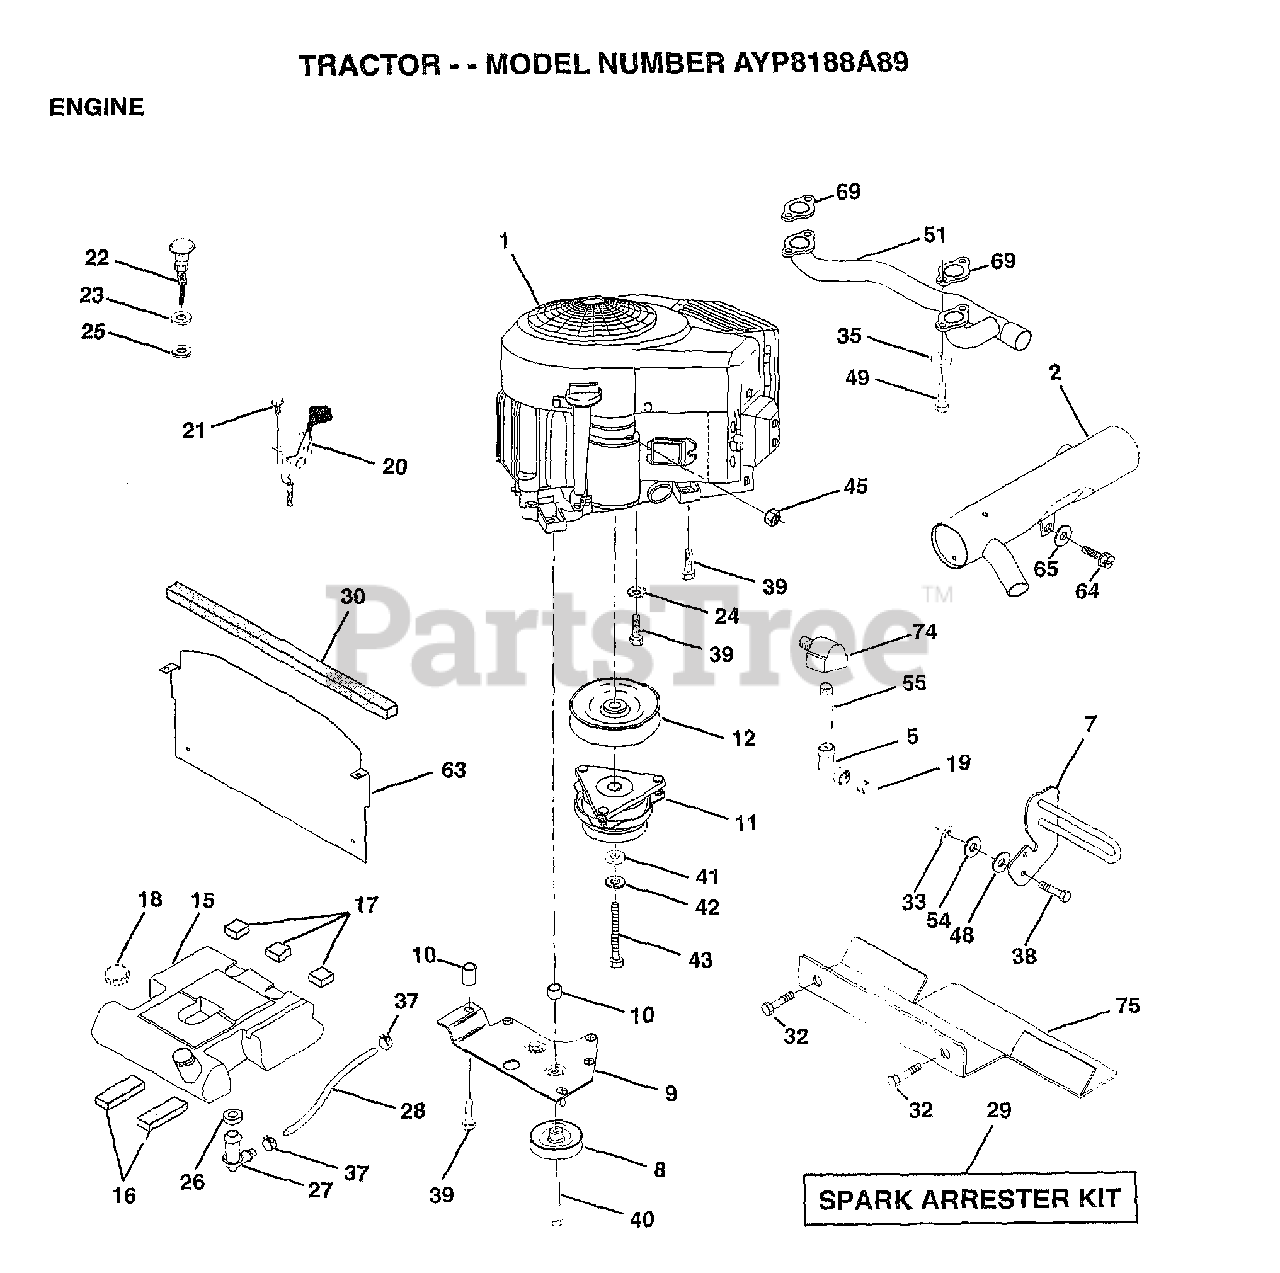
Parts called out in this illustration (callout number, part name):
2	MUFFLER SIDE1-1/8
4	PIPE NIPPLE LT
5	ELBOW
7	GUARD.MUFFLER.ASM
9	KEEPER ASM BELT
10	BUSHING.
12	PULLEY.ENG.CLUTCH
15	TANK FUEL REAR
16	PAD IDLER TI
17	PAD-SPACER LT
18	CAP ASM FUEL
19	PLUG T
21	SCREW LT
22	CHOKE CONTROL
23	WASHER
24	LOCKWASHER
25	"NUT,KEPS 3/8-24IM"
26	BUSHING OUTLET T
27	STEM.TANK.FUEL
29	SPARK ARREST KIT
30	FOAM-STRIP LT
33	NUT
35	LOCKWASHER
37	HOSE CLAMP
38	"BOLT,HEX"
39	SCREW.3/8-16X2.25
40	SCREW.TT.3/8-16X4
41	WASHER
42	LOCKWASHER
43	BOLT.7/16-20X4.25
45	NUT
48	WASHER T
49	SCREW
51	PIPE.MANIFOLD
54	WASHER
63	HEAT.SHIELD.VGT.
64	SCREW
65	WASHER
69	GASKET MUFFLER
74	ELBOW STREET BASS
75	SHIELD.HEAT.INTEK.VGT
